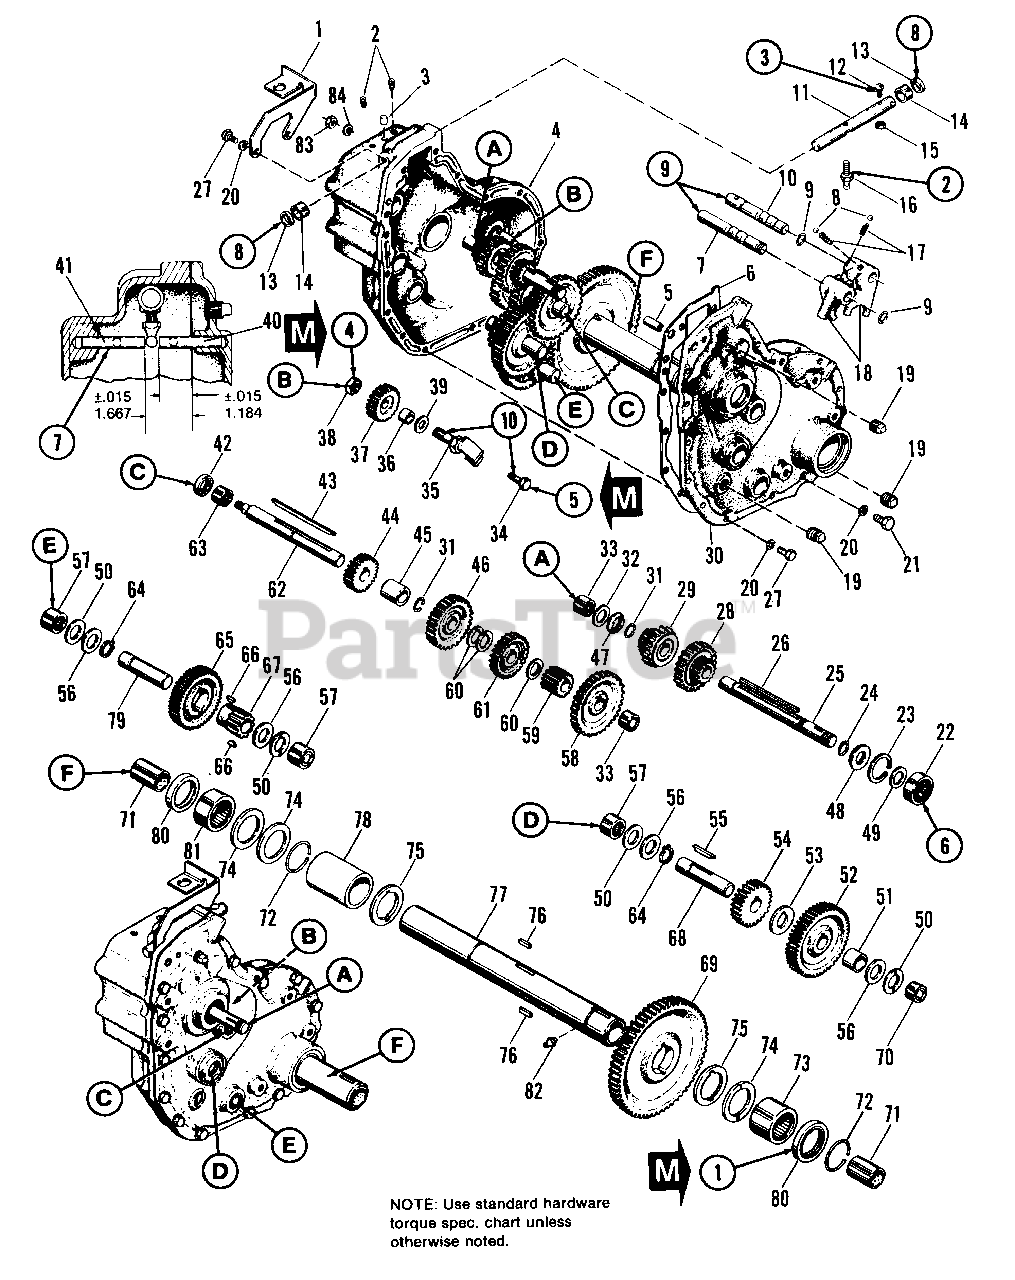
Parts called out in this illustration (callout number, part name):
1	SUPPORT, Switch
2	SETSCREW, 5/16-18 x 1/2
4	CASE ASSY., Gear
5	PIN, Roll, 3/8 x 1
6	GASKET, Gear Case
7	SHAFT, Shifter, Reverse, Med.
8	BALL, Shiftlock
9	RING, Retaining
10	SHAFT, Shifter, Hi-Lo
11	ROD, Shift
12	BOLT, Carriage, Special, 5/16-18 x 1-1/4
14	SPACER, Diff.
15	LOCKNUT, Hex, Jam, 5/16-18
16	STEM, Shift
18	FORK, Shift
19	PLUG, Pipe, 3/8
20	LOCKWASHER, 5/16
21	CAPSCREW, Hex Hd., 5/16-18 x 1-1/2
22	BEARING, Ball
23	RING, Retaining
24	RING, Retaining
25	SHAFT, Pulley
27	CAPSCREW, Hex Hd., 5/16-18 x 1
30	COVER ASSY., Gear Case
31	RING, Retaining
33	BEARING, Needle
34	SCREW, Hex, Whizlock Flange, 3/8-16 x 1-1/4
35	PIN ASSY., Rev. Gear
37	GEAR, Reverse
38	LOCKNUT, Hex, 1/2-20
40	PIN ASSY., Roll
41	PIN ASSY., Roll
44	PINION, Reverse & II
46	GEAR, Driven II
52	GEAR, 2nd Intermediate
54	PINION, 2nd Intermediate
57	BEARING, Needle
58	GEAR, Driven I
59	PINION, Driven 1st Intermediate
61	PINION, Driven III
62	SHAFT, 1st Intermediate
63	BEARING, Needle
64	RING, Retaining
65	GEAR, 3rd Intermediate
66	KEY, Woodruff, #6
67	PINION, 3rd Intermediate
68	SHAFT, 2nd Intermediate
69	GEAR, Drive
70	BEARING, Needle
73	BEARING, Needle
74	WASHER, Axle Tube
75	WASHER, Axle Tube
77	TUBE & BUSHING ASSY.
79	SHAFT, 3rd Intermediate
81	BEARING, Needle
82	FITTING, Grease
83	NUT, Hex, 3/4-16
84	LOCKWASHER, 3/4
